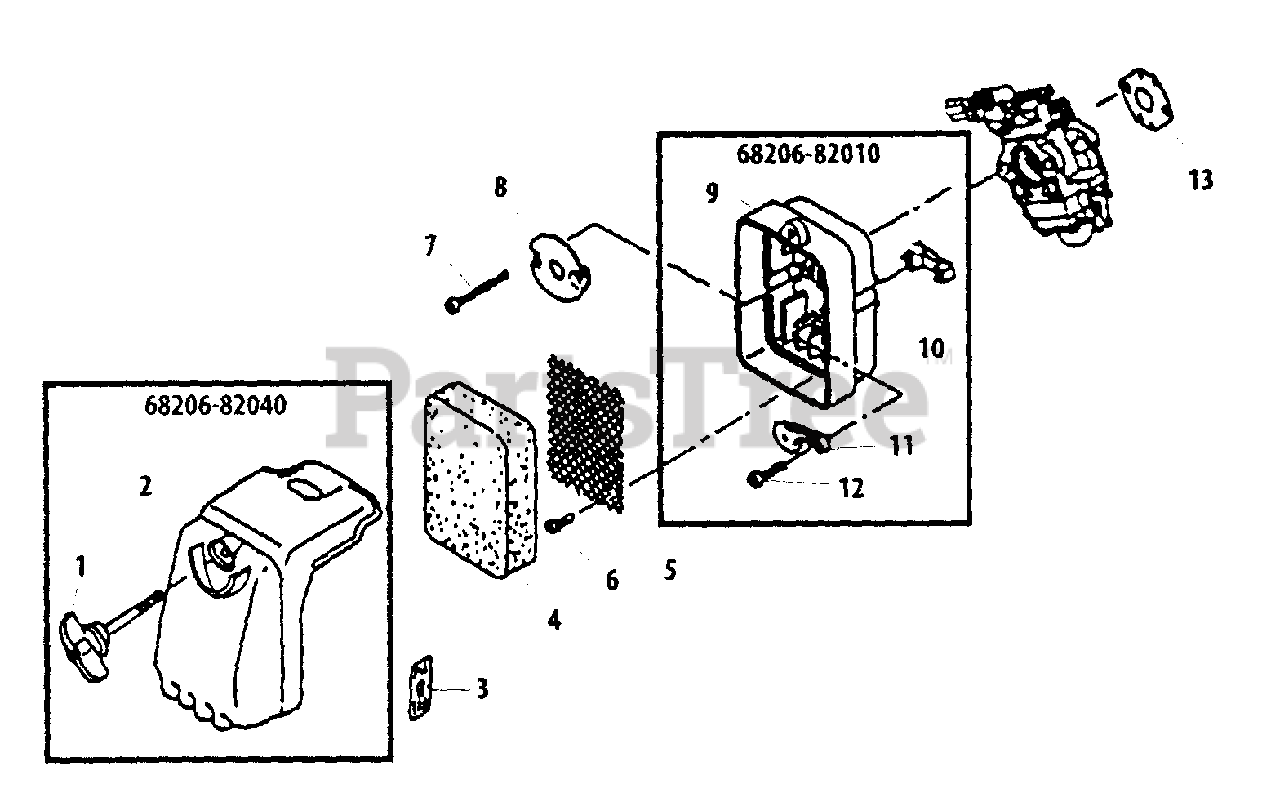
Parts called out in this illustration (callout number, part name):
1	AIR FILTER COVER ASSY
2	COVER, AIR FILTER
3	LABEL - CHOKE
4	FILTER, AIR
5	SCREEN, SPARK ARRESTOR
6	SCREW - TAPPING
7	SCREW - 5X60
8	PLATE, PREVENT
9	CASE, AIR FILTER
10	LEVER, CHOKE
11	PLATE, SHUTTER
13	GASKET, INTAKE
68206-82010	CASE, AIR FILTER
68206-82040	AIR FILTER COVER ASSY
